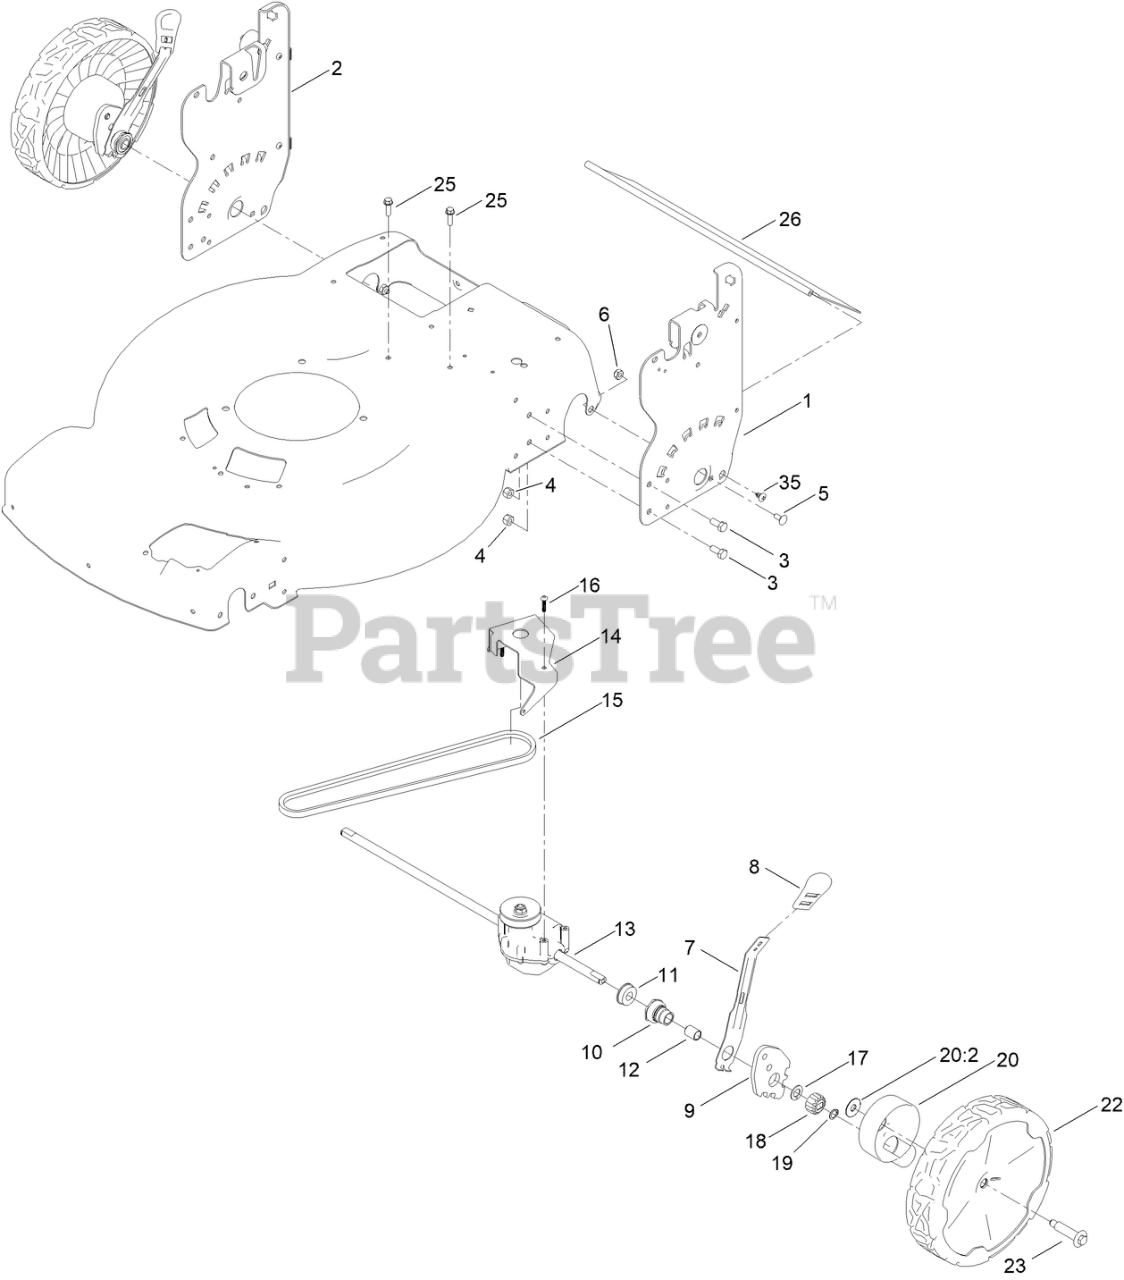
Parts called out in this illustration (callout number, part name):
1	PLATE-HOC, LH
2	PLATE-HOC, RH (2 HOLE)
3	SCREW-HH
4	NUT-LOCK, NI
5	SCREW-CARR
6	NUT-LOCK, NI
7	ARM-SPRING
8	KNOB-HOC
9	ARM-PIVOT, REAR
10	RETAINER-BUSHING, HOC
11	BEARING-BALL
12	BUSHING-SLEEVE
13	TRANSMISSION-RWD
14	BRACKET-TRANSMISSION
15	V-BELT
16	SCREW-PLASTITE
17	WASHER-THRUST
18	GEAR-PINION, 15T
19	RING-RETAINING
20	ASM-COVER, GEAR (DK GRAY)
20:2	WASHER-STEPPED
22	ASM-9.65" WHEEL, GEARED
23	WHEEL BOLT
25	SCREW-HWH
26	SHIELD-TRAILING
35	SCREW-PTH
